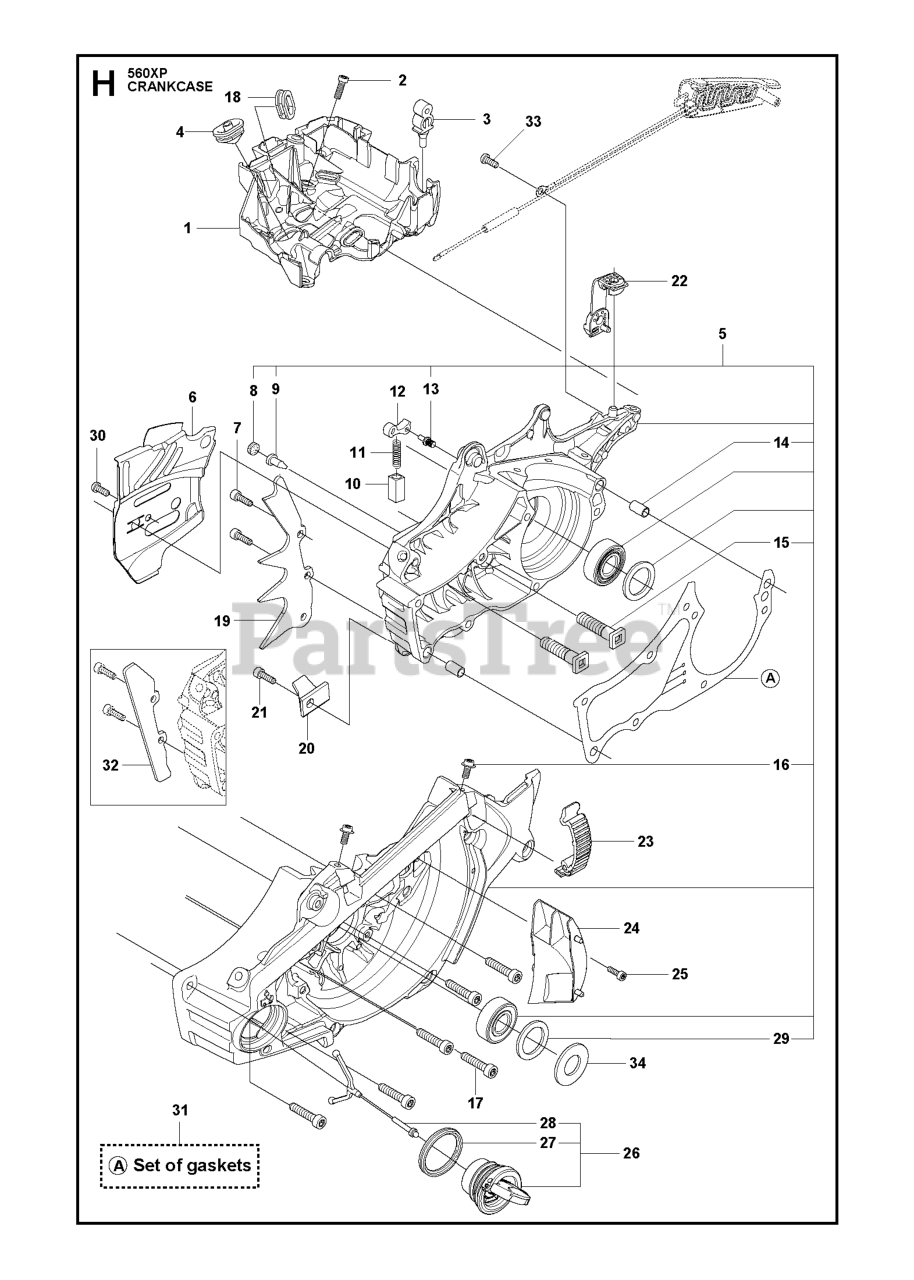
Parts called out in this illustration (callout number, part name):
1	Carburetor base
2	SCREW ITXSCFM
6	CHAIN GUIDE PLATE
7	SCREW ITXPANM M5X16 T27 10.9
8	PLUG
9	VALVE-CHECK (DUCKBILL)
11	LOCK SPRING
14	GUIDE BUSHING
16	SCREW ITXSCM WASHER M5X12 T27
17	SCREW ITXSCM M5X25 12.9 TBO T
20	CHAIN CATCHER
22	DEFLECTION LIMITER
23	CLIP GRAY
24	AIR NOZZLE
25	SCREW ITXSCM M4X15 T27 12.9 T
26	TANK CAP ASSY
29	RADIAL SEAL
30	SCREW CITXPANT
31	GASKET KIT
34	CAPS
